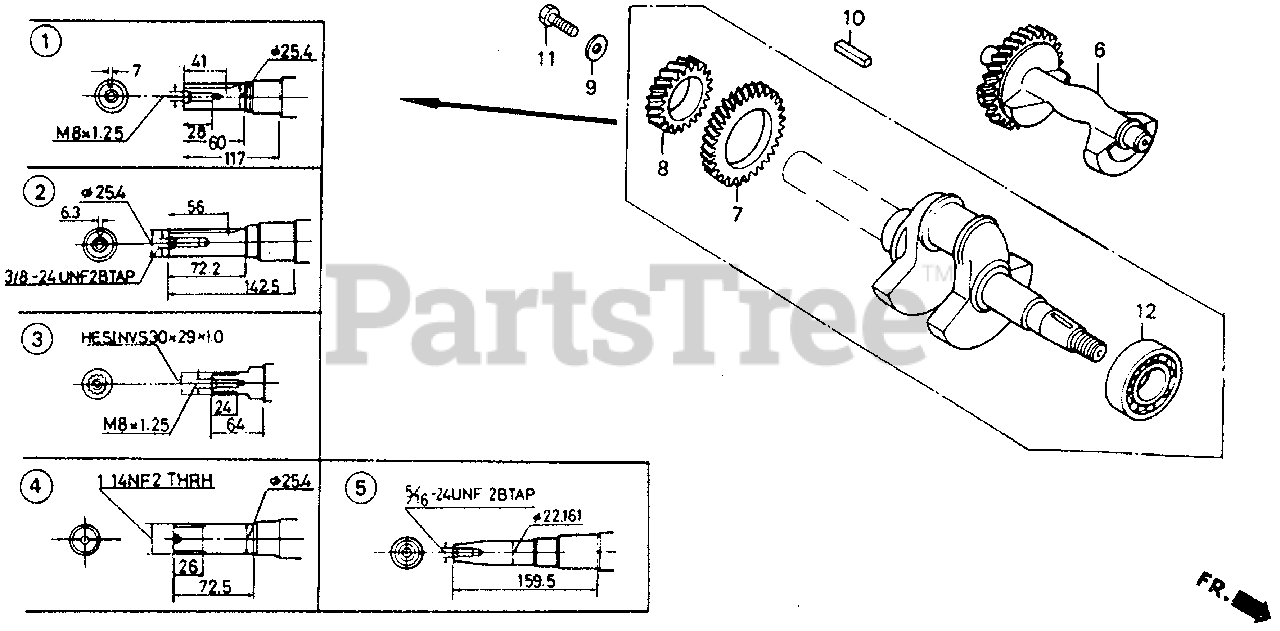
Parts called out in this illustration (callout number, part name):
2	CRANKSHAFT (Q-TYPE)
6	WEIGHT, BALANCER
7	GEAR, BALANCER DRIVE
8	GEAR, TIMING
10	KEY (6.3X6.3X43)
12	BEARING, RADIAL BALL (6207)
